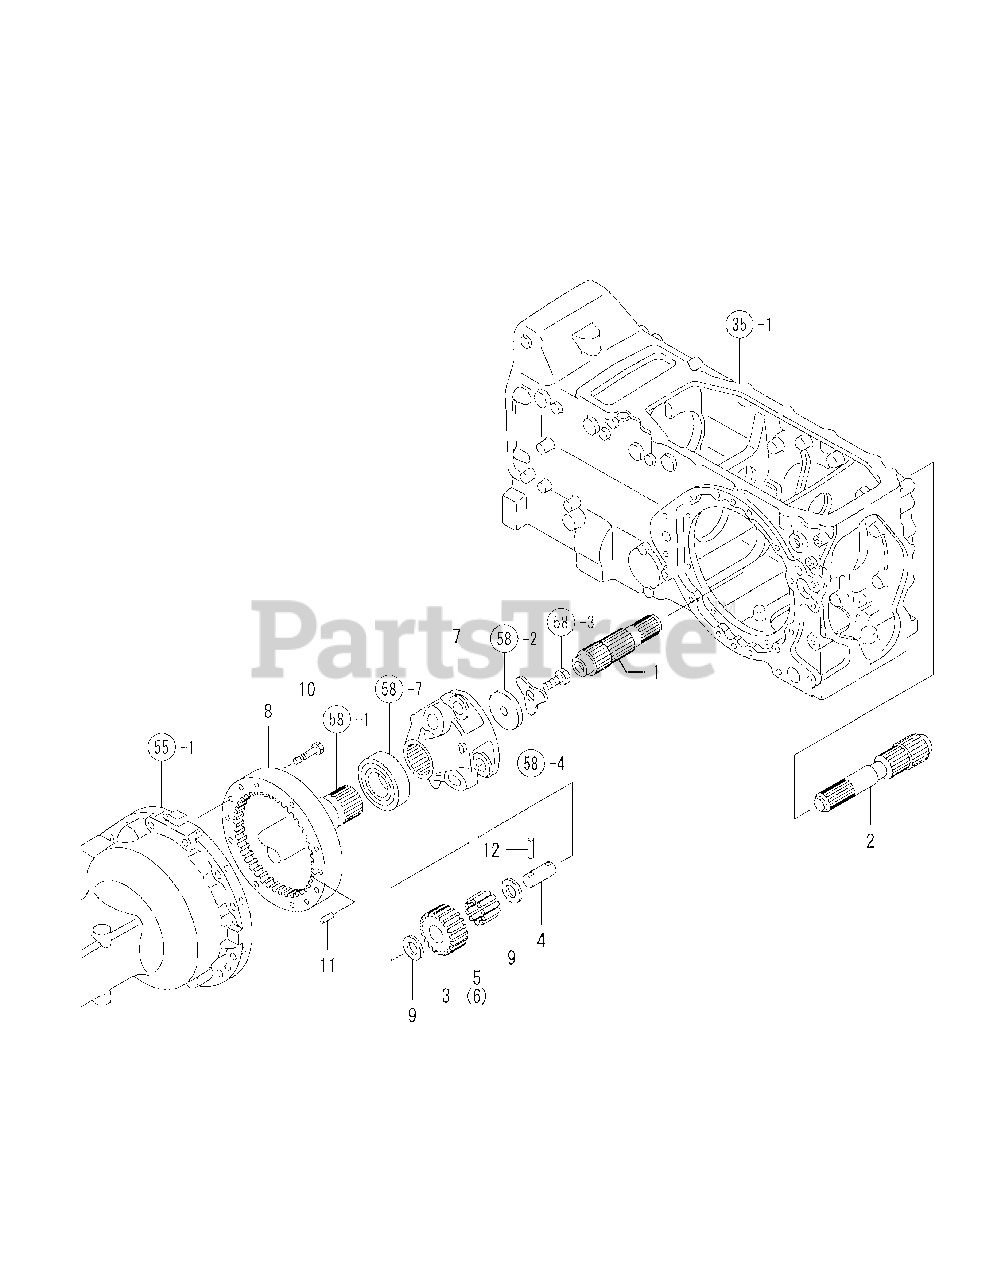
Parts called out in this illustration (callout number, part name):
3	PINION, PLANETARY
4	SHAFT, PLANETARY
7	CARRIER, PLANETARY
8	GEAR, INTERNAL
9	WASHER 26X42X 1
11	PARALLEL PIN 10X 18
12	SPRING PIN 8X40
